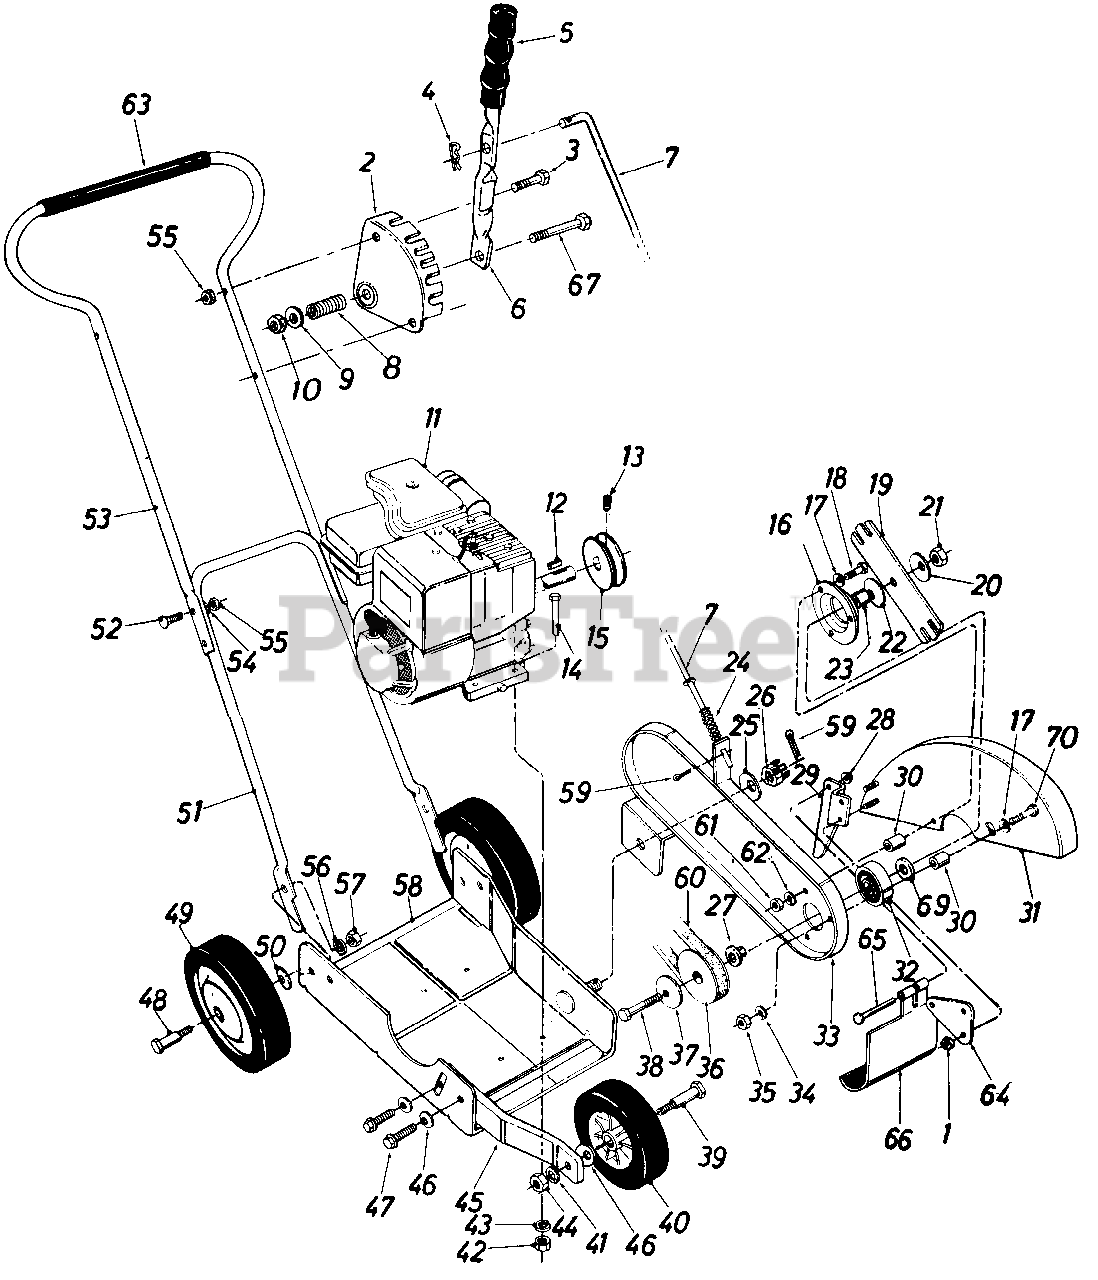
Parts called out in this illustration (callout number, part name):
1	Hex Cent. L.-Nut 1/4-2 Thd.
3	Hex Bolt 1/4-20 x 1.25" Lg.*
4	Cotter Pin 1/8" Dia. x 1.0" Lg.*
5	Grip
7	Clutch Rod
8	Compression Spring .50" O.D. x 1.38" Lg.
9	Fl.-Wash .34" I.D. x .62" O.D. x.063
10	Hex Cent. L.-Nut 5/16-18 Thd.
11	Engine
12	Sq.Key 3/16 x 1.0" Lg.*
13	Set Scr. 1/4-28 x 1/4" Lg.
14	Hex Bolt 5/16-18x 1.50' Lg.*
15	Engine Pulley
16	Bearing Housing
17	Bell.-Wash. .34" I.D. x 88" O.D. x .060
18	Hex Bolt 5/16-18 x 1.25" Lg.*
20	Bell.-Wash. .535" I.D. x 1.50" O.D. x.052
21	Hex Cent. L.-Nut 1/2-20 Thd.
22	Bell.-Wash. .535" I.D. x 1.50" O.D. x .052
23	Spacer
24	Compression Spring .57" O.D. x 1.92" Lg.
25	Bell.-Wash. .535" I.D. x 1.50" O.D. x.052
26	Hex Castle Nut 1/2-20 Thd.
27	Shoulder Spacer
28	Push Cap
29	Guide
30	Spacer.354" I.D. x.635" O.D. x .510" Lg.
33	Spindle Bracket Ass'y.
34	L.-Wash. 5/16" I.D.*
35	Hex Nut 5/16-18 Thd.
36	Pulley
37	Bell.-Wash. .535" I.D. x 1.50" O.D. x.052
38	Hex Bolt 1/2-20 x 3.50" Lg.*
39	Shoulder Bolt .498" Dia. x 1 .450
40	Wheel Ass'y. Comp. 6" Dia. x 1.50
41	L.-Wash. 3/8" I.D.*
42	Hex Nut 5/16-18 Thd.*
43	L.-Wash.5/16" I.D.*
44	Hex Nut 3/8-16 Thd.*
45	Front Wheel Support
46	Bell.-Wash. .400" I.D. x 88" O.D. x.060
47	Hex Wash. Hd. Self Tap Scr. 3/8- 16 x .75 " Lg.
48	Shoulder Bolt.498" Dia. x 1.450
49	Wheel Ass'y. Comp. 7" Dia. x 1.50
50	Bell.-Wash. .400" I.D. x 88" 0.D.
51	Lower Handle
52	Carriage Bolt 1/4-20 x 1.25" Lg.*
53	Upper Handle
54	L.-Wash. 1/4" I.D.*
55	Hex Nut 1/4-2 Thd.*
56	L.-Wash. 3/8" I.D.*
57	Hex Nut 3/8-16 Thd.*
58	Base Ass'y.
59	Cotter Pin 1/8" Dia. x 1.0" Lg.*
60	3V-Belt31.2" Lg.
61	Hex Nut 5/16-18 Thd.#
62	L.-Wash. 5/16" I.D.*
64	Flap Bracket
65	Hinge Pin
66	Debris Deflector
67	Hex Bolt 5/16-18 x 1.75" Lg.*
69	Fl.-Wash. .51 I.D. x 1.00 O.D. x .060
70	Hex Bolt 5/16-18 x 2.00" Lg.*
